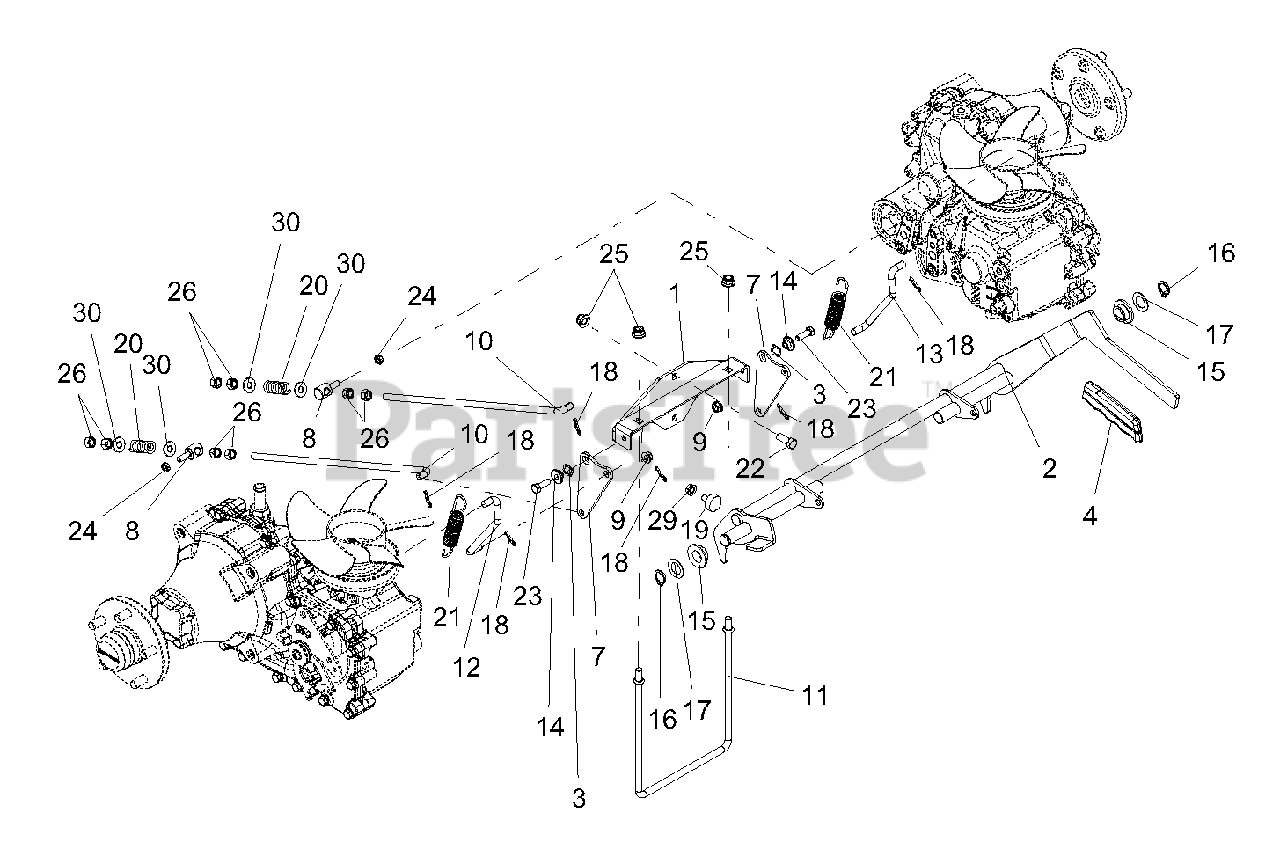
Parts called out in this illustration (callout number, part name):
1	WMT, SPRING ANCHOR BRKT
2	WLDMT, PARKING BRAKE LEVER
3	WAVE WASHER .531X.781X.125 FH
4	GRIP, PARKING BRAKE
7	PLATE, BRAKE PIVOT
8	TRUNNION, .31-18
9	NUT, LK-TOP-FLG .312-18 YWZC
10	ROD, BRAKE ADJ.
11	ROD, BRAKE MTG
12	LINKAGE, RH BRAKE ACTUATING
13	LINKAGE, LH BRAKE ACTUATING
14	BSHG.-FLG. .312 X .500 X .344
15	BUSHING, FLANGE
16	RG-RING-EXT .689 X .078
17	WHST-HDND-THRST
18	PIN, HAIR
19	BUMPER, RUBBER
20	SPRING, COMPRESSION
21	EXT. SPRING
22	BLT-HEX .38-16X1.00 GR5 YWZC
23	BLT-HEX .31-18X1.00 GR5 YWZC
24	NUT-LK-CTR-JAM .31-18 YWZC
25	NUT-LK-NYL-FLG .38-16 YWZC
26	NUT-HEX .38-16 YWZC
29	NUT-SPNLK-FLG .312-18 YWZC
30	WSHR-FL-STL.38X.875X.083 YWZC
